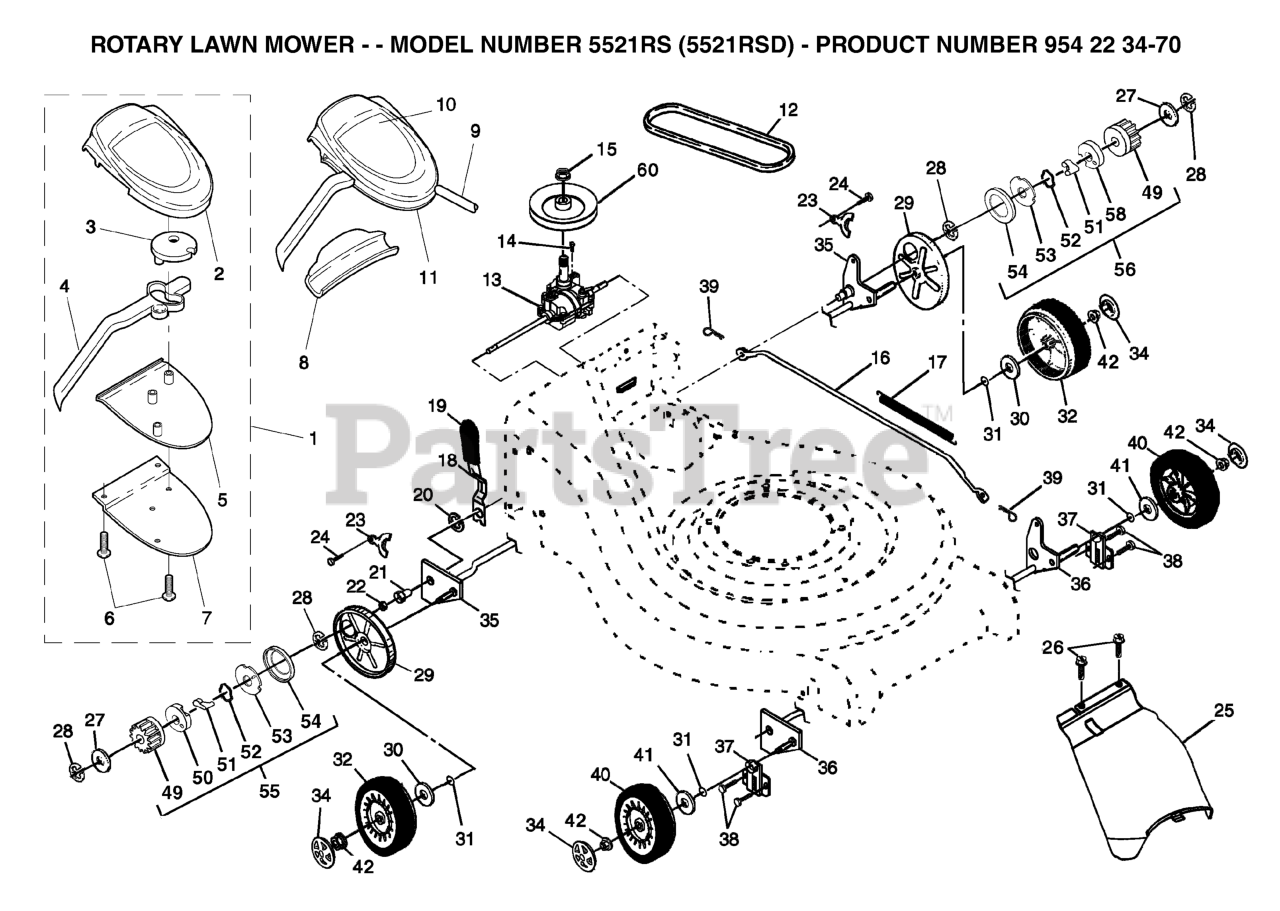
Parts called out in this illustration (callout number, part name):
1	CONTROL.WALK.EZ.BLACK
2	COVER, DRIVE CONTROL, TOP
3	PULLEY.CAM.DRIVE.CONTROL.HV
4	LEVER, AUTOWALK DRIVE CONTROL
5	COVER, DRIVE CONTROL BOTTOM
6	SCREW, PHILLIPS HEAD 10 X 5/8
7	BRACKET, DRIVE CONTROL
8	EZ WALK SNAP COVER PLATE
9	CABLE, DRIVE CONTROL
10	DECAL.DRIVE.CONTROL.HV
12	V-BELT
13	TRANSMISSION.21.RWGD.EZ/AW/VS
15	FLANGED LOCKNUT 3/8-16 ZINC
16	ROD CONNECTING
17	SPRING
18	SPRING SELECTOR
19	KNOB, SELECTOR SPRING
21	RP BEARING SUPPORT
22	BEARING, BALL
23	BRACKET
25	COVER DRIVE
28	E-RING 7/16 RE
29	COVER.DUST.WHEEL
30	WASHER FLUT
31	O-RING
32	WHEEL.9X2.PR.LP.RADIAL.BK.BB.3
34	HUBCAP
35	SHAFT ASM. REAR
36	SHAFT ASSY
37	RETAINER.FRONT.SHAFT
39	RETAINER CLIP
40	WHEEL ASMBLY FRONT
41	WASHER.FLAT.1/2
42	HEX FLANGE LOCKNT
49	GEAR, PINION
50	RETAINER, DRIVE, RH
51	PAWL.DRIVE.21.EZ-WALK
52	SPRING, TORSION
53	DISC.DRIVE.21.EZ-WALK
54	SEAL.PINION
55	PINION ASSY, RH
56	PINION ASSY, LH
58	RETAINER.DRIVE.21.EZ-WALK.LT
60	RP PULLEY DRIVE
